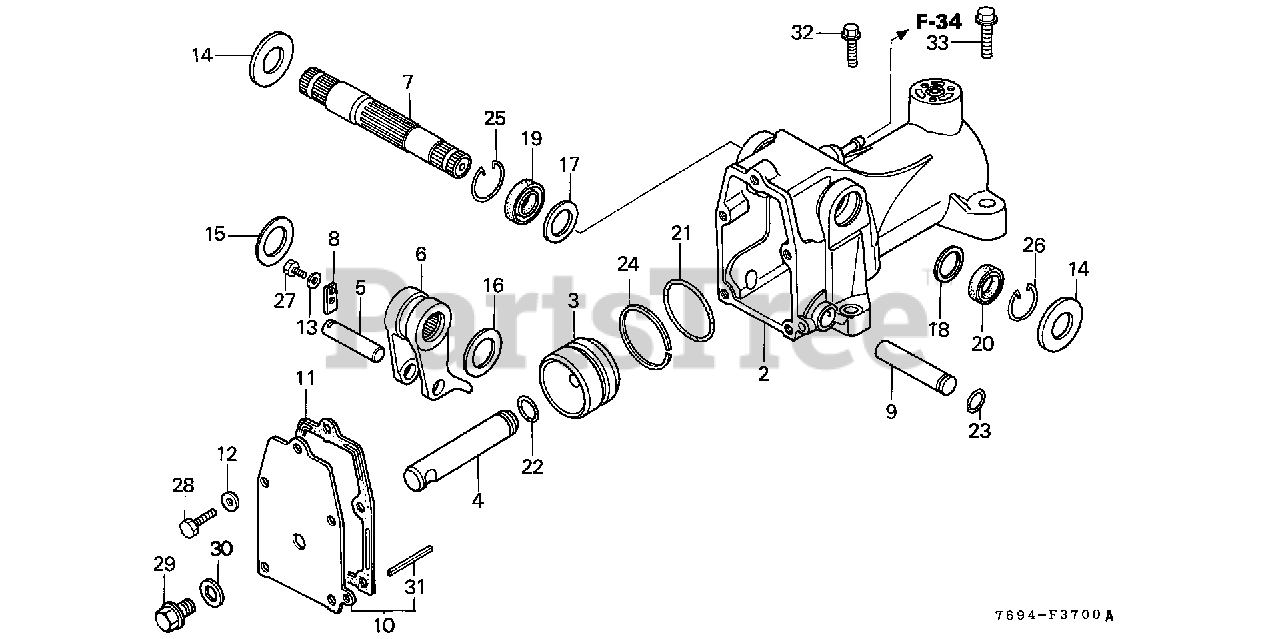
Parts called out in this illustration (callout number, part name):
2	CYLINDER, HYDRAULIC
3	PISTON, HYDRAULIC (60MM)
4	ROD, CONNECTING
5	PIN, CONNECTING ROD
6	ARM, HYDRAULIC CYLINDER
7	SHAFT, HYDRAULIC CYLINDER
8	PLATE, CONNECTING ROD PIN
9	SHAFT, STOPPER
10	COVER, CYLINDER
11	GASKET, HYDRAULIC CYLINDER COVER
12	WASHER (8MM)
13	WASHER, CONICAL SPRING (6MM)
14	WASHER, THRUST (25.5X50X5)
15	WASHER, PLAIN (INNER) (28.5MM)
16	WASHER, PLAIN (INNER) (25.5MM)
17	WASHER, PLAIN (OUTER) (30.5MM)
18	WASHER, PLAIN (OUTER) (25.5MM)
19	OIL SEAL (30X44X8)
20	OIL SEAL (25X38X9)
21	O-RING, HYDRAULIC CYLINDER
22	O-RING (17X3.5)
23	O-RING (13.8X2.4)
24	RING, BACK-UP
25	RING, STOPPER (49)
26	RING, STOPPER (43)
27	BOLT, HEX. (6X12)
28	BOLT, HEX. (8X22)
29	BOLT, DRAIN PLUG (14MM)
30	WASHER, DRAIN PLUG (14MM)
31	PIN, SPRING (6X40)
32	BOLT, FLANGE (10X55)
33	BOLT, FLANGE (12X58)
33	BOLT, FLANGE (12X50)
